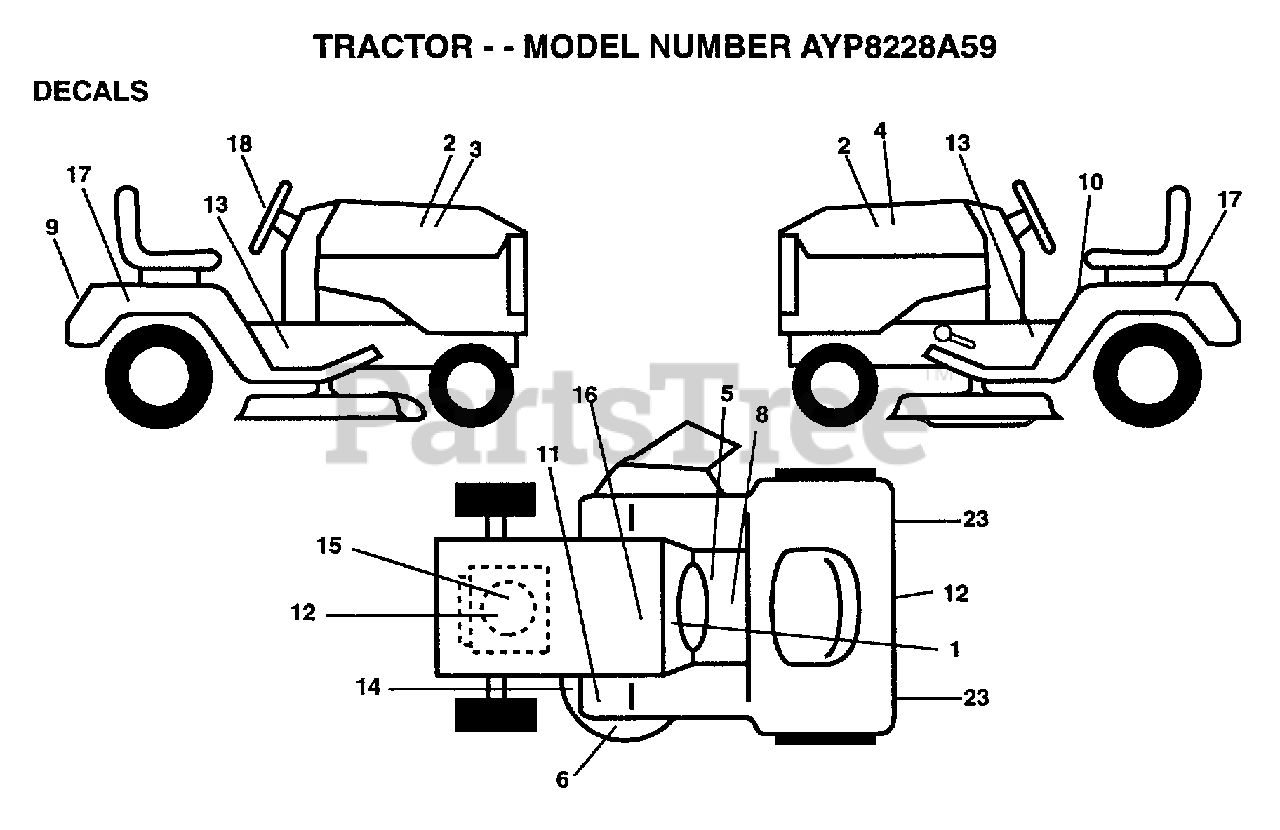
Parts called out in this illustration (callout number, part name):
1	DECAL.DASH.INST.
2	NAMEPLATE.HD.WIZA
3	DECAL HD RH WIZ +
4	DECAL HD LH WIZ +
5	DECAL BRAK PARK
6	DECAL DECK WIZ +
8	DECAL SADLE HYDRO
10	DECAL
12	DECAL D-BAR CNTRL
13	DECAL CHASSIS 50
14	"DECAL.V.BELT.44"""
15	DECAL.ENG.KOHLER.
16	DECAL.BATRY.3-3908
17	DECAL.FENDER.WIZ
18	DECAL INS STG WHL
19	DCL.PNL.SD.KOHL.
23	REFLECTOR-TAIL YT
